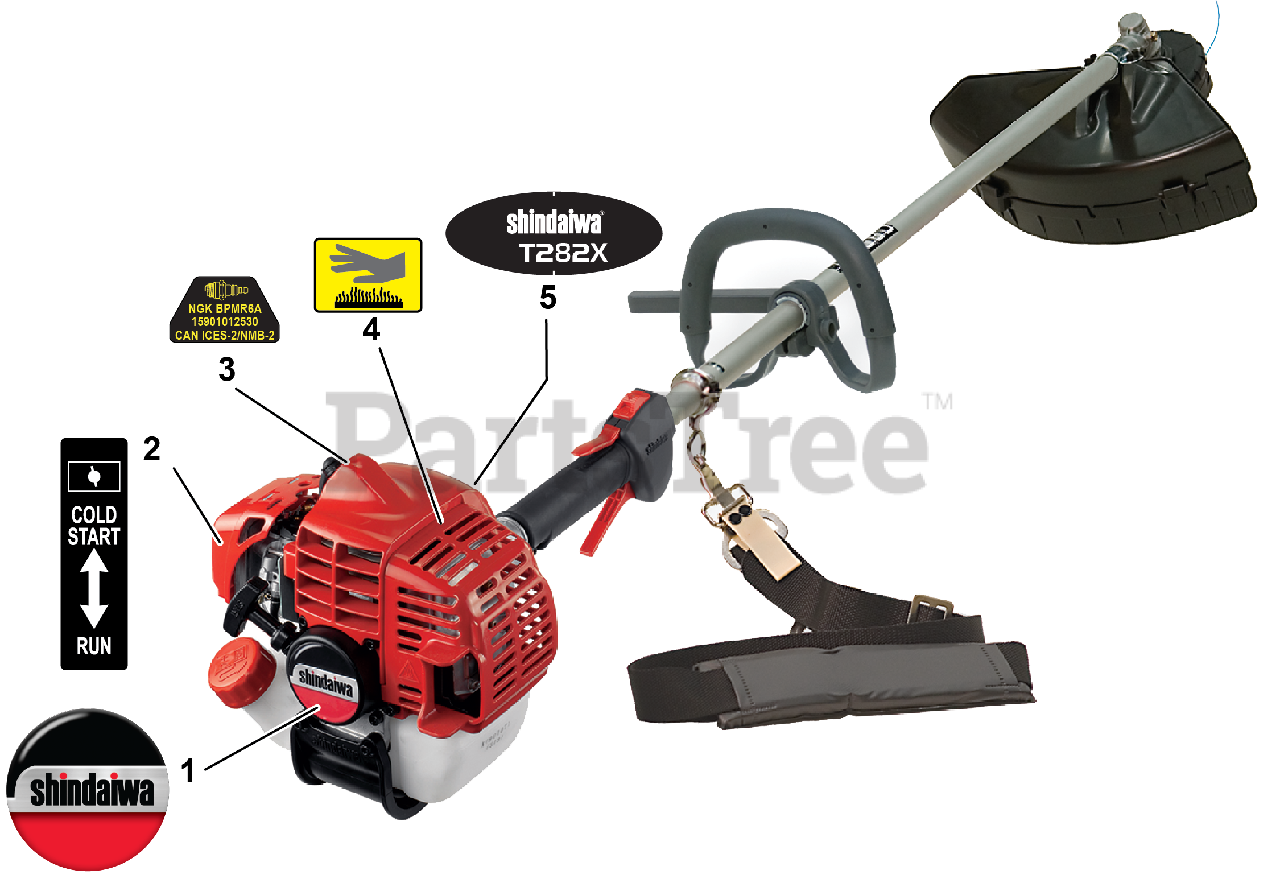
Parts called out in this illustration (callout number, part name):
1	LABEL - RECOIL STARTER
2	LABEL - CHOKE
3	LABEL - SPARK PLUG - BPMR6A
4	LABEL - CAUTION - HOT
5	LABEL - MODEL T282X
